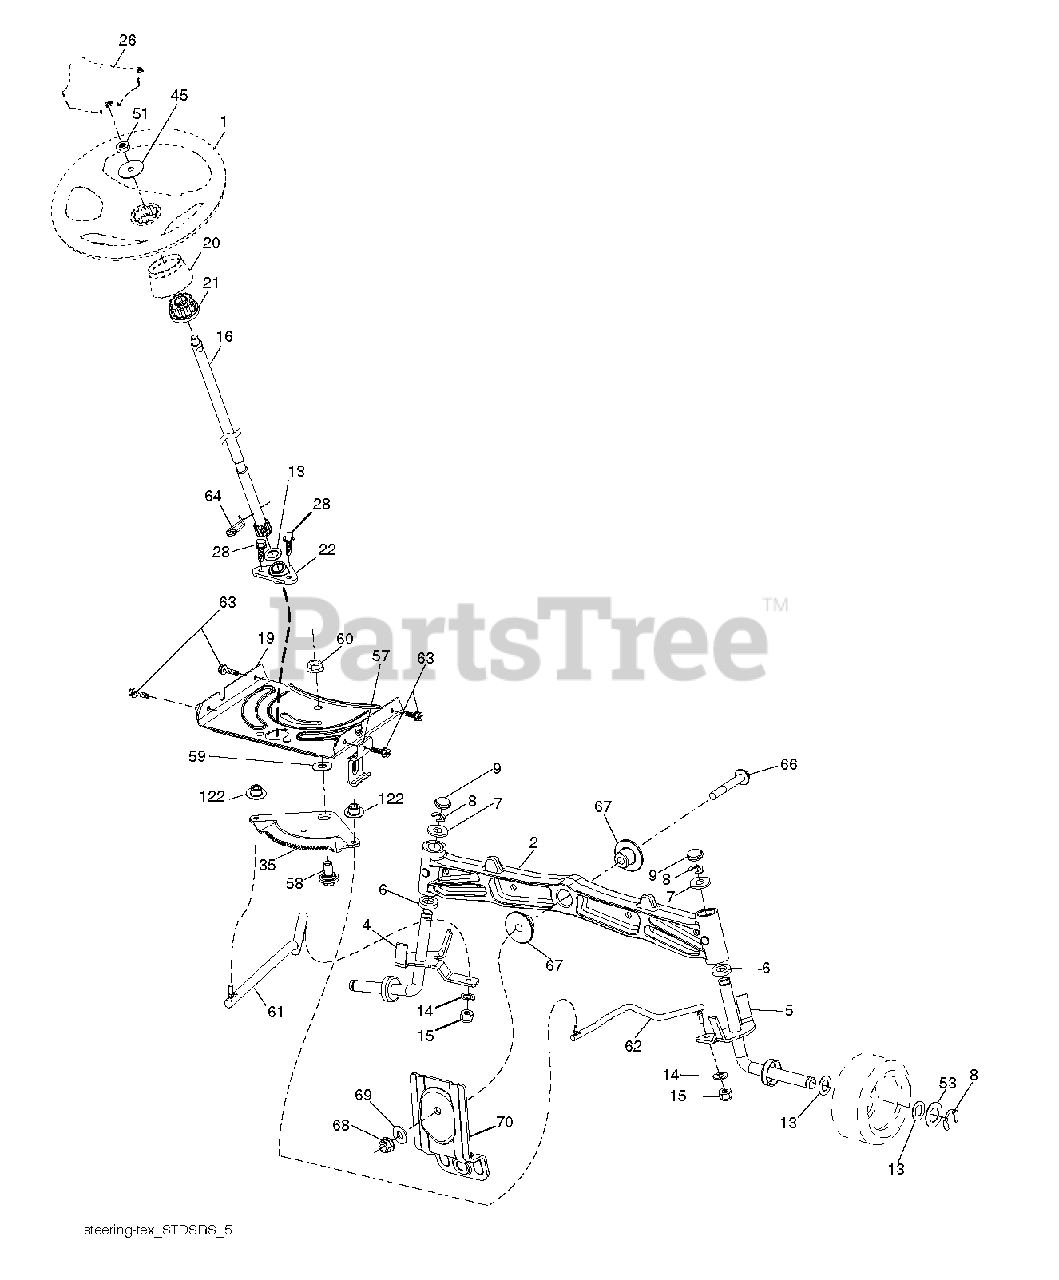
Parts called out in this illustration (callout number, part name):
1	WHEEL, STEERING
4	SPINDLE.WELDED.LH.15"T
5	SPINDLE.WELDED.RH.15"T
6	BRNG T
14	WASHER, LOCK 3/8
15	NUT CROWNLOCK 3/8-24
19	PLATE.STEER.DDL.NLT/NG
20	BOOT.STEERING.
21	ADAPTER, WHEEL STNG
22	STEERING.SUPT.LOWER.
26	INSERT, WHEEL STEERING
28	SCREW, 3/8-16X3/4
35	GEAR.SECTOR.PLATE.DDL.
57	BRKT.UPSTOP.GT/LT.TEX
58	BOLT.SHOULDER.SECTOR.P
59	WASHER.THURST.SECTOR.S
60	NUT FLANGE LOCK 5/8-11
61	DRAGLINK.LH.BALLSTUD.D
62	DRAGLINK.RH.BALLSTUD.D
63	SCREW
64	RETAINER.CLIP.SPRING.S
66	BOLT HEX FGHD 7/16-14 X 3 SERR
67	BUSHING.PM.FRONT AXLE
68	NUT.LOCK.FLANGE.7/16
69	WASHER.1.5X.505X.118
70	BRKT.DECK.SUSPENSION.F
